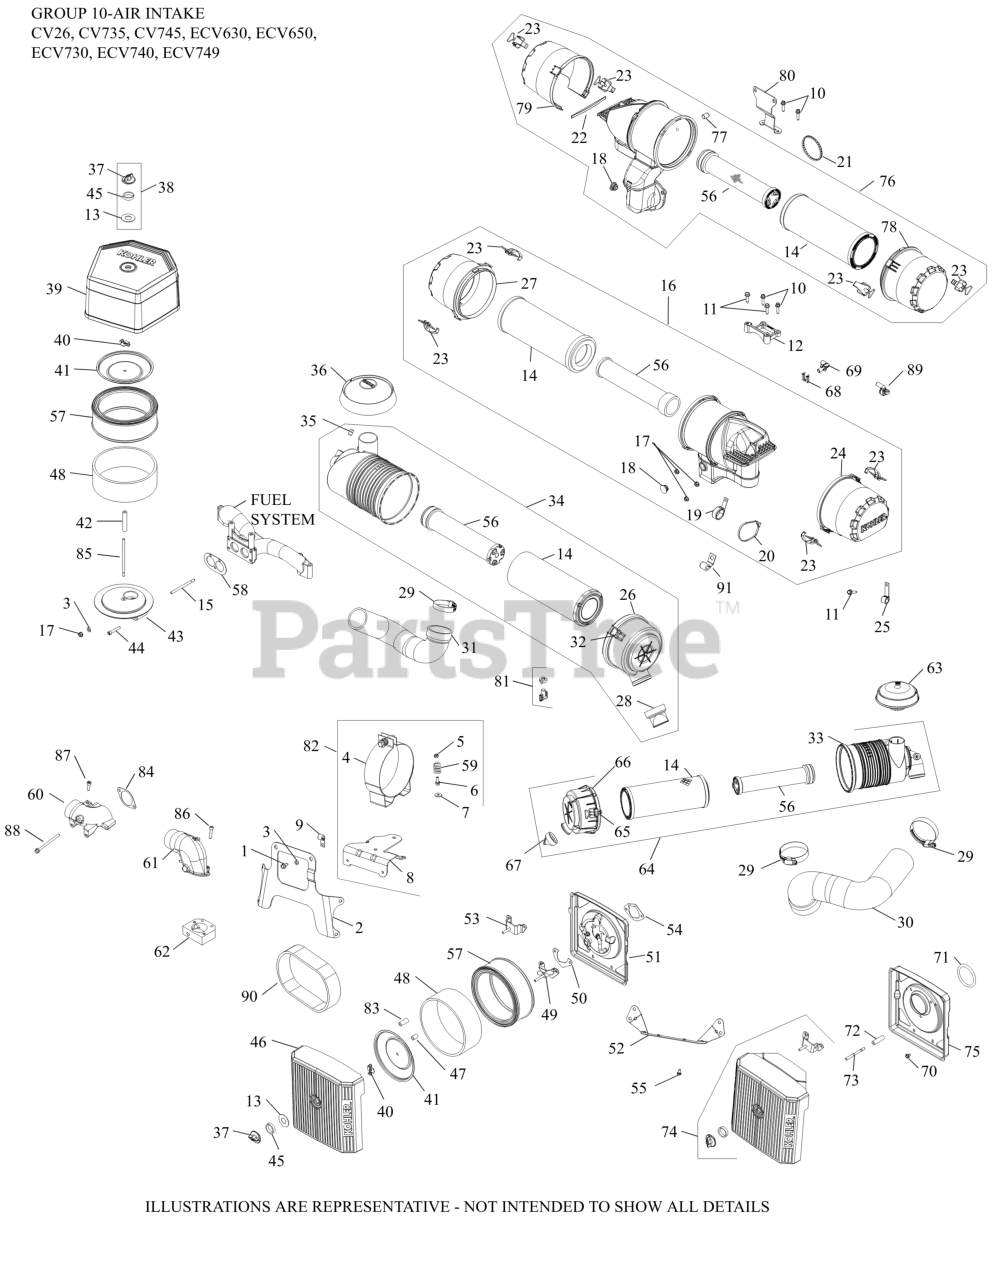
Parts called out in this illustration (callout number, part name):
10	SCREW, FLG M6X1.0X25
11	SCREW, THREAD FORMING
12	AIR CLEANER BRACKET
14	ELEMENT, AIR FILTER - PRIMARY
16	FILTER, AIR ASSEMBLY
18	PLUG, HOLE
21	O-RING (HDAC SEAL-EFI)
22	DAMPER, FOAM INSERT
23	CLIP ASSEMBLY
25	CLIP, CABLE
56	ELEMENT, AIR FILTER - SAFETY
78	COVER, AIR FILTER
79	COVER, RAIN CAP
